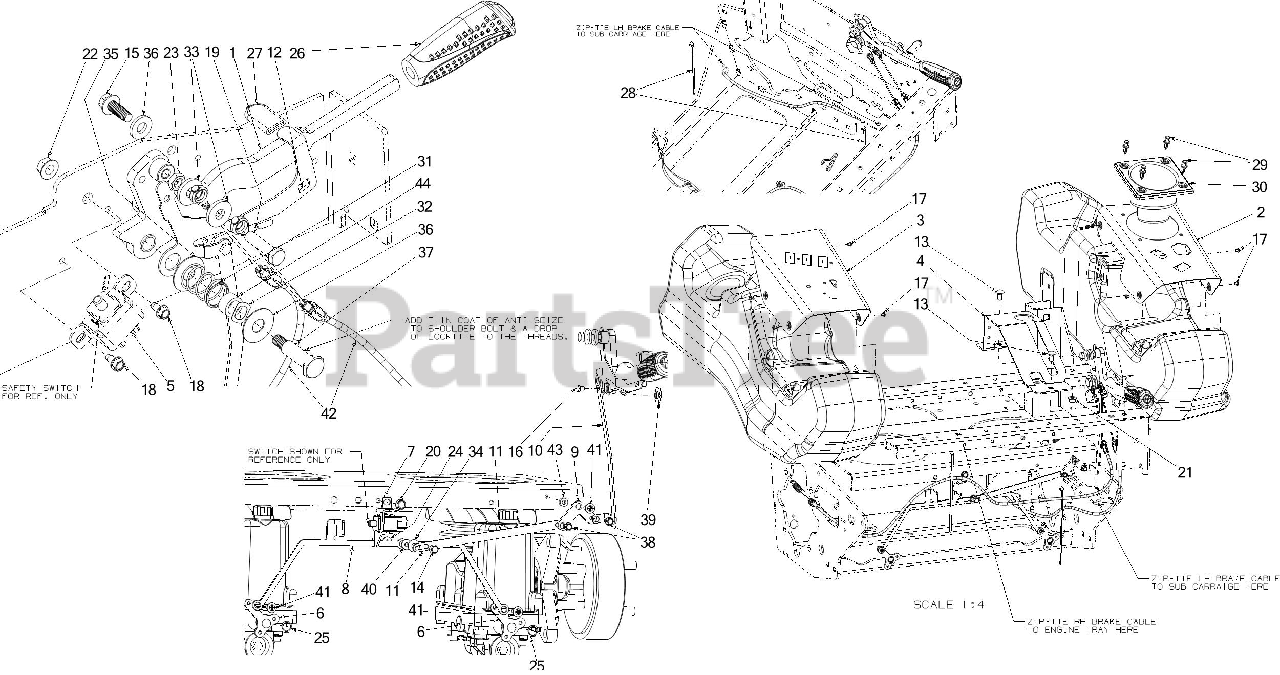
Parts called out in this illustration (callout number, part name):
1	BRAKE HANDLE ASSEMBLY
2	CONTROL PANEL (LH)
3	CONTROL PANEL (RH)
4	BRAKE BOOT BRACKET
5	BRAKE PANEL MOUNT
6	TRANSMISSION BYPASS LEVER
7	NEUTRAL BRACKET
8	DUMP VALVE BRACKET
9	NEUTRAL CONTROL LEVER
10	NEUTRAL ARM LINK
11	NEUTRAL ARM LINK
12	RELEASE VALVE LEVER
13	CARRIAGE BOLT 3/8-16 x .750 GR5
14	SCREW 1/4-20 x .75 GR5
15	SCREW 3/8-16 x 1
16	SCREW M6 x 8MM
17	SCREW #10-32 x .25
18	SCREW 1/4-20 X.500
19	SCREW 3/8-16 x 1.50 GR8
20	SCREW 5/16-18 x .500
22	HEX LOCK NUT
24	LOCK NUT 1/4
25	SNAP RING
27	SEAT ADJUSTER GRIP
28	7" CABLE TIE
29	PLASTIC RIVET
30	CUP HOLDER
31	COMPRESSION SPRING .844X.970X1.50
32	WAVE WASHER
33	FLAT WASHER .385 x 1.00 x .135
34	FLAT WASHER .283 ID x .749 x .030
35	FLAT WASHER
36	FLAT WASHER
37	SHOULDER SCREW .498 DIA x 1.450-THD
38	SHOULDER SCREW
39	SHOULDER SPACER
40	SHOULDER SPACER
41	SHOULDER SCREW .375X.280:1/4-14
42	BRAKE CABLE
